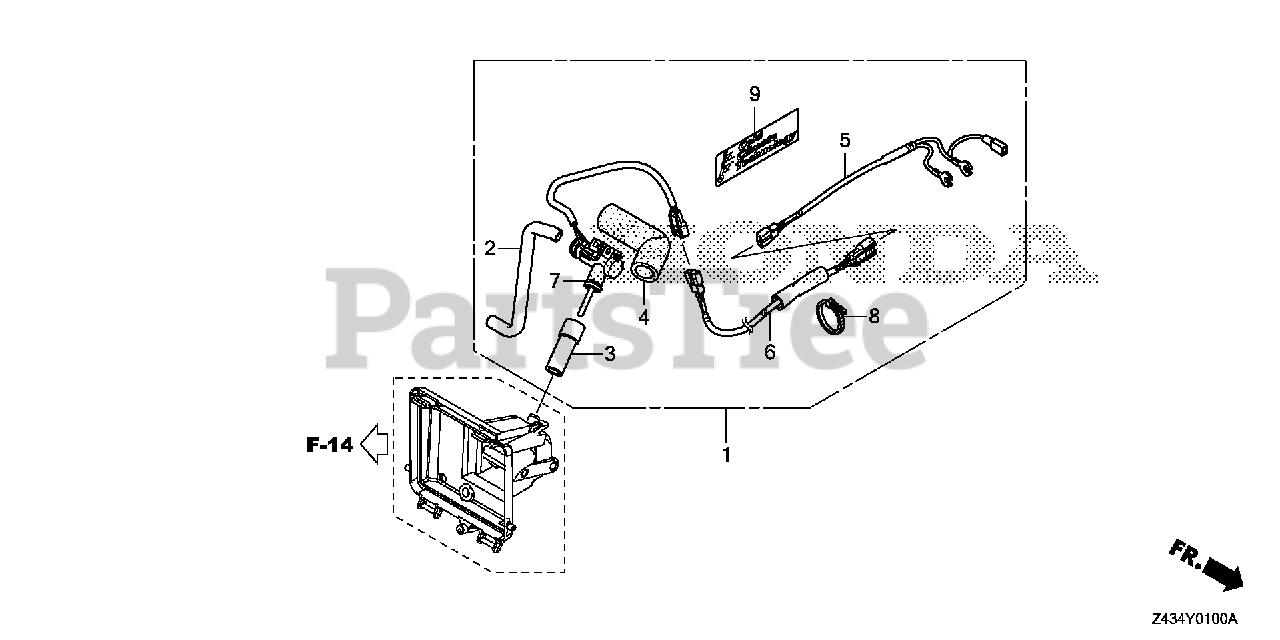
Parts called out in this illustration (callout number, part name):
1	HEATER KIT, BREATHER
2	TUBE A, BREATHER
3	TUBE B, BREATHER
4	INSULATOR, BREATHER TUBE
5	SUB-WIRE ASSY.
6	SUB-WIRE ASSY.
7	HEATER ASSY., BREATHER (L)
8	TIE, CABLE
9	MARK (CCT)
